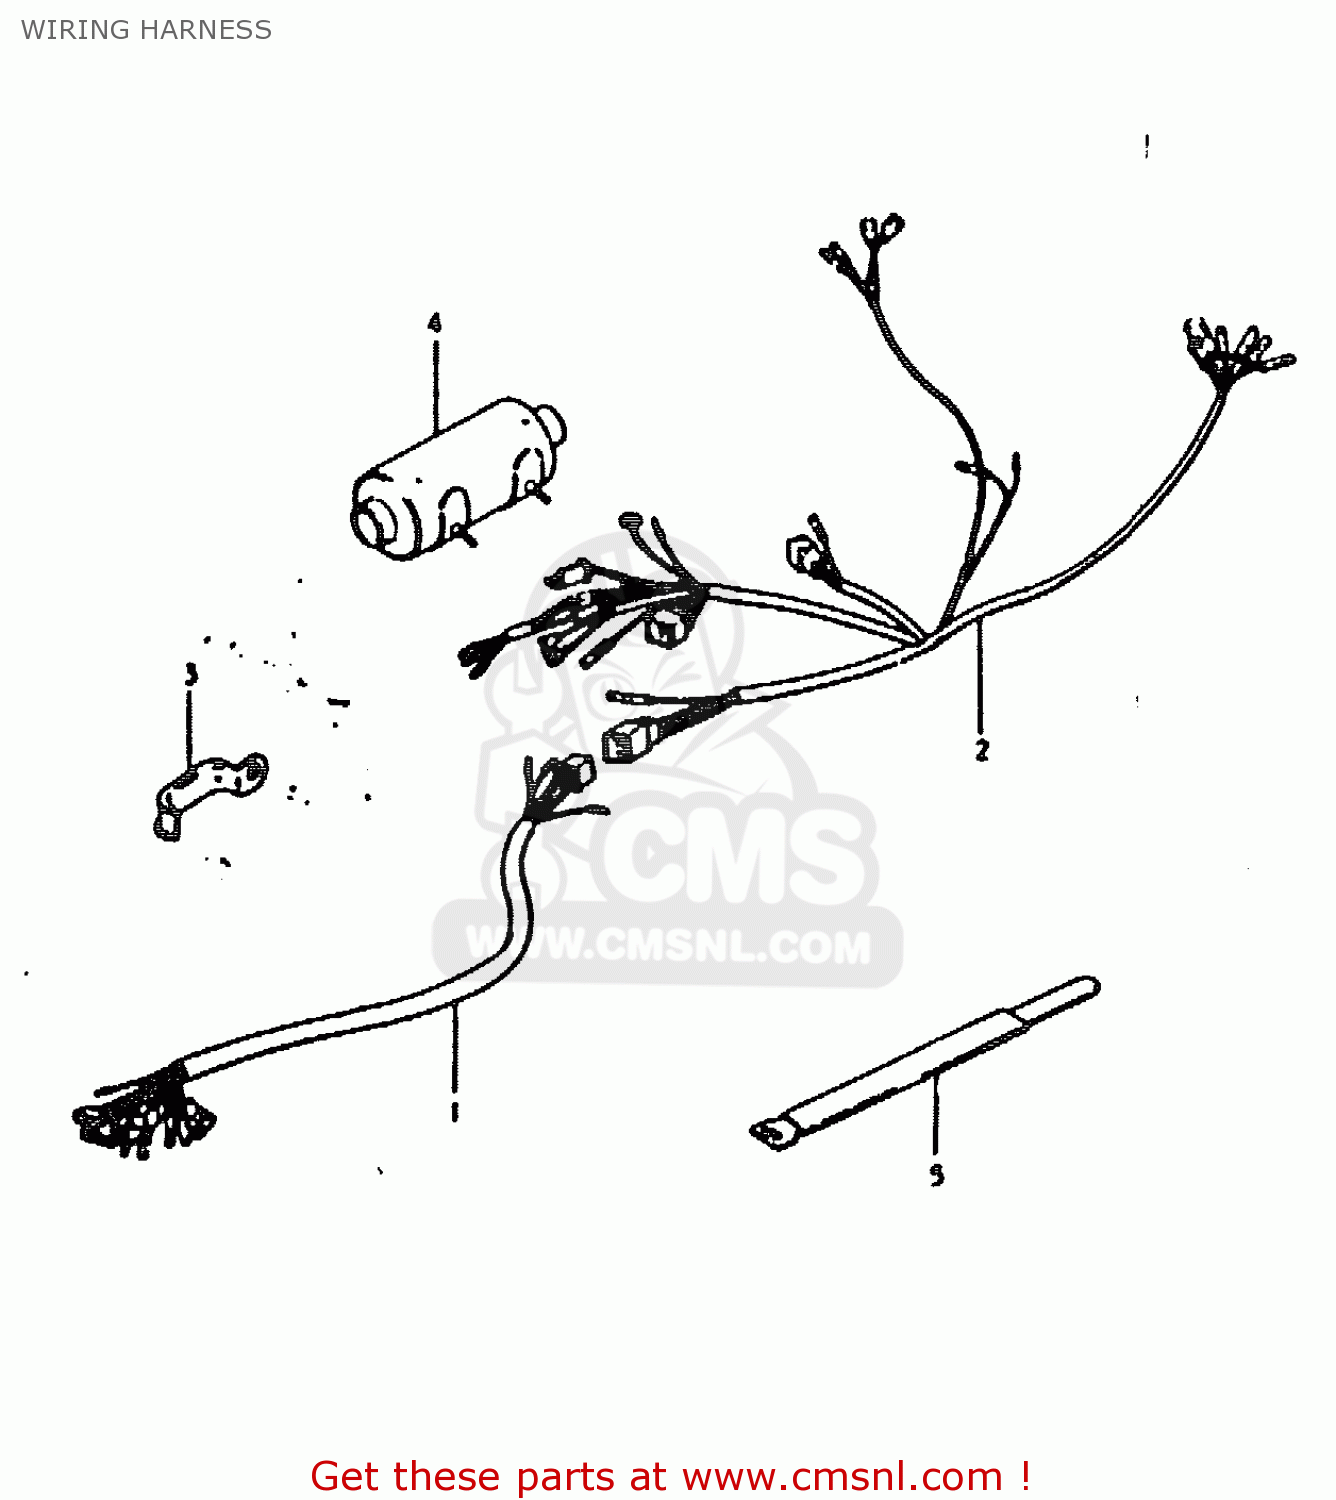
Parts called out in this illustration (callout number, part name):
1	WIRING HARNESS NO.1
2	WIRING HARNESS NO.2
3	CLAMP
4	BOOT
5	CLAMP
